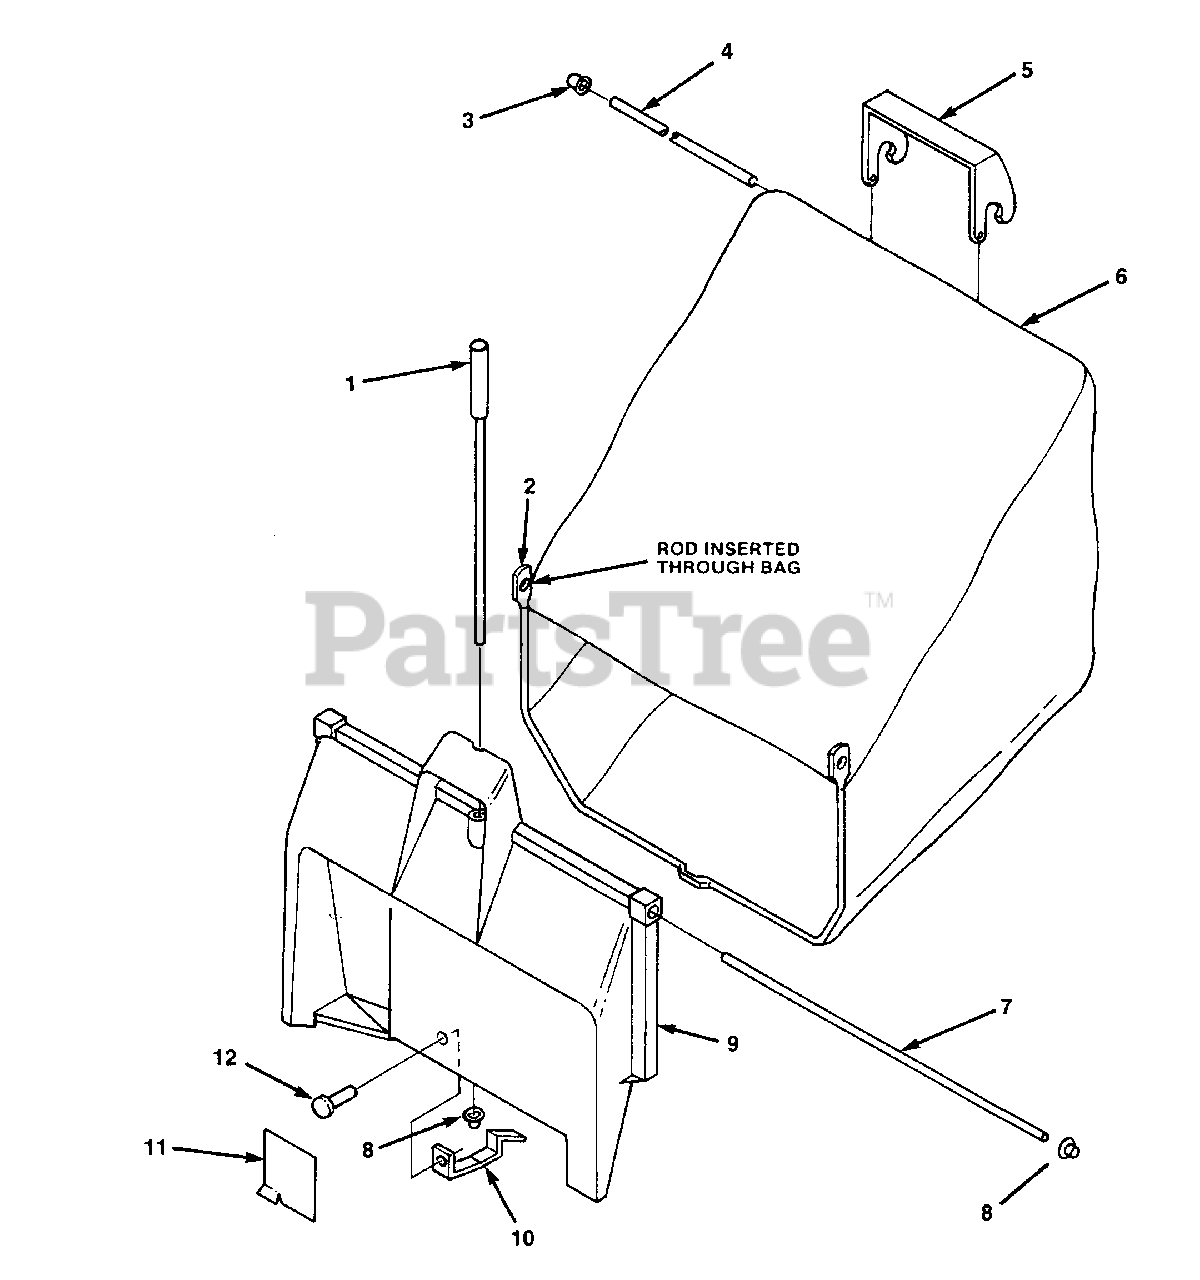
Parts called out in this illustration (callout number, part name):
1	LATCH- Rod
2	ROD- Bag Support
4	ROD- Upper bag
5	HANDLE
6	CATCHER- Grass
7	ROD- Bag hinge
9	ADAPTOR- Bag
11	DEFLECTOR
